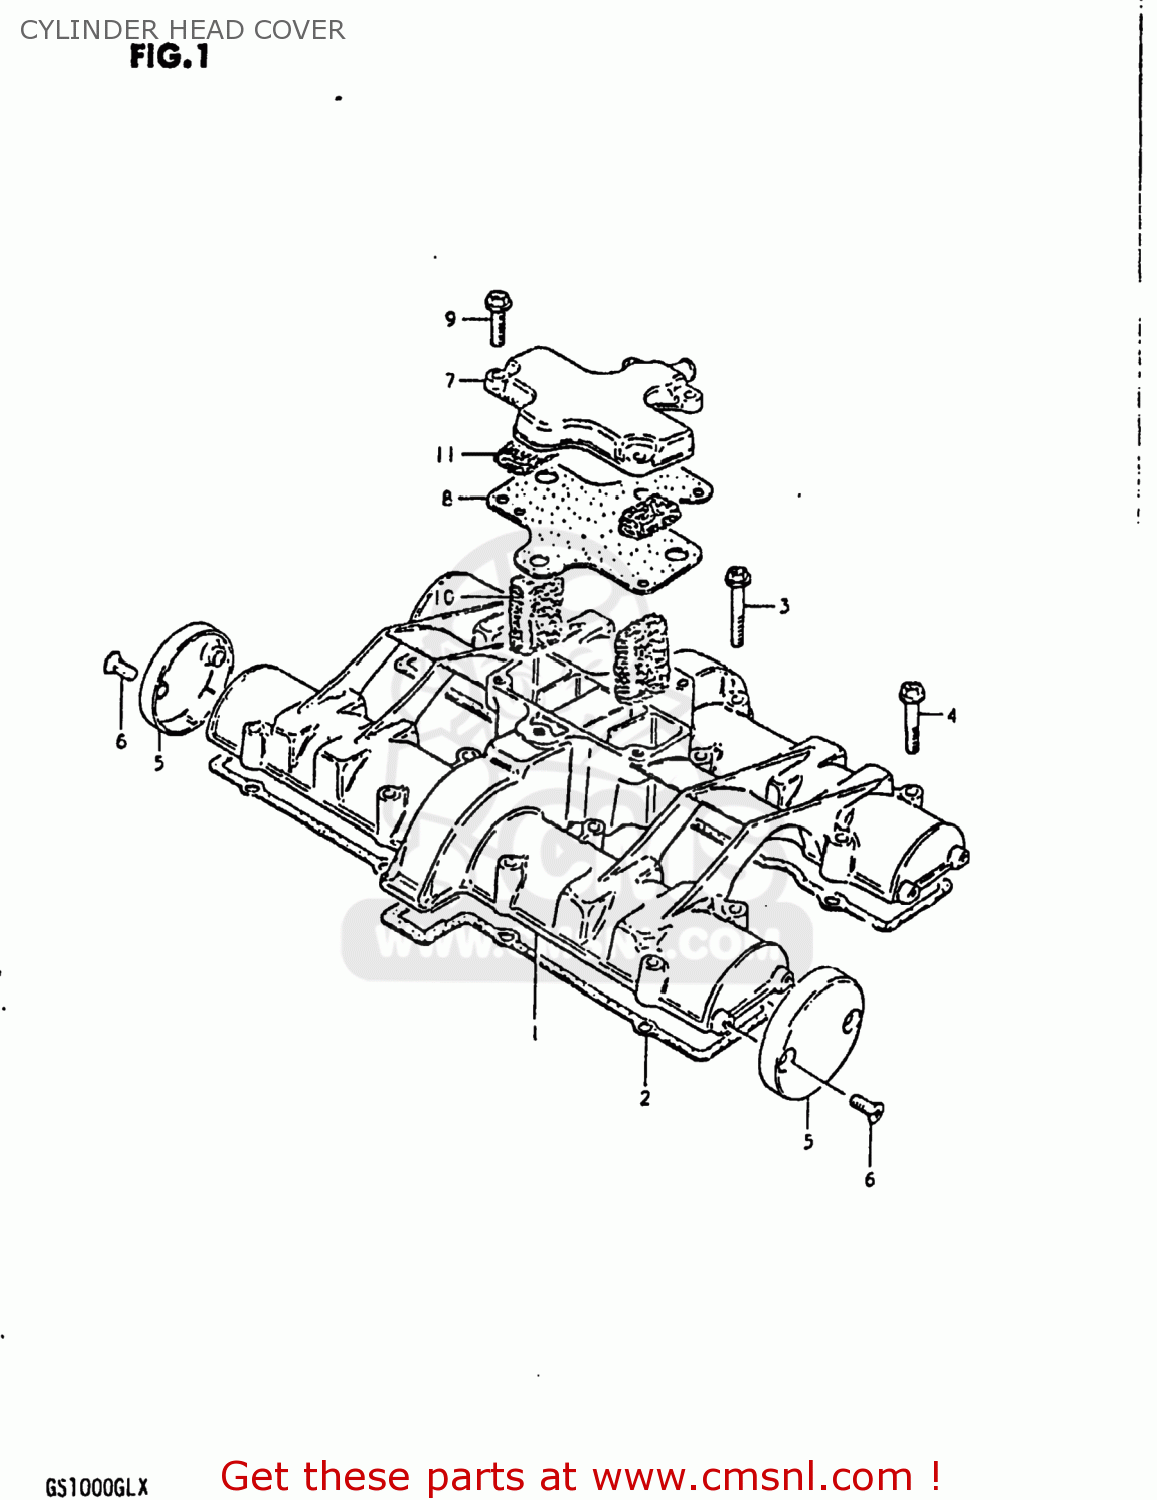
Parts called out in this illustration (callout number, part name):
1	COVER,CYLINDER HEAD
2	GASKET,CYLINDER HEAD COVER (MCA)
3	BOLT
4	BOLT 6X35
5	CAP,CYLINDER HEAD COVER
6	SCREW 5X12
7	COVER,BREATHER
8	GASKET (MCA)
9	BOLT
10	COVER,BREATHER
11	SEPARATOR,OIL BREATHER
